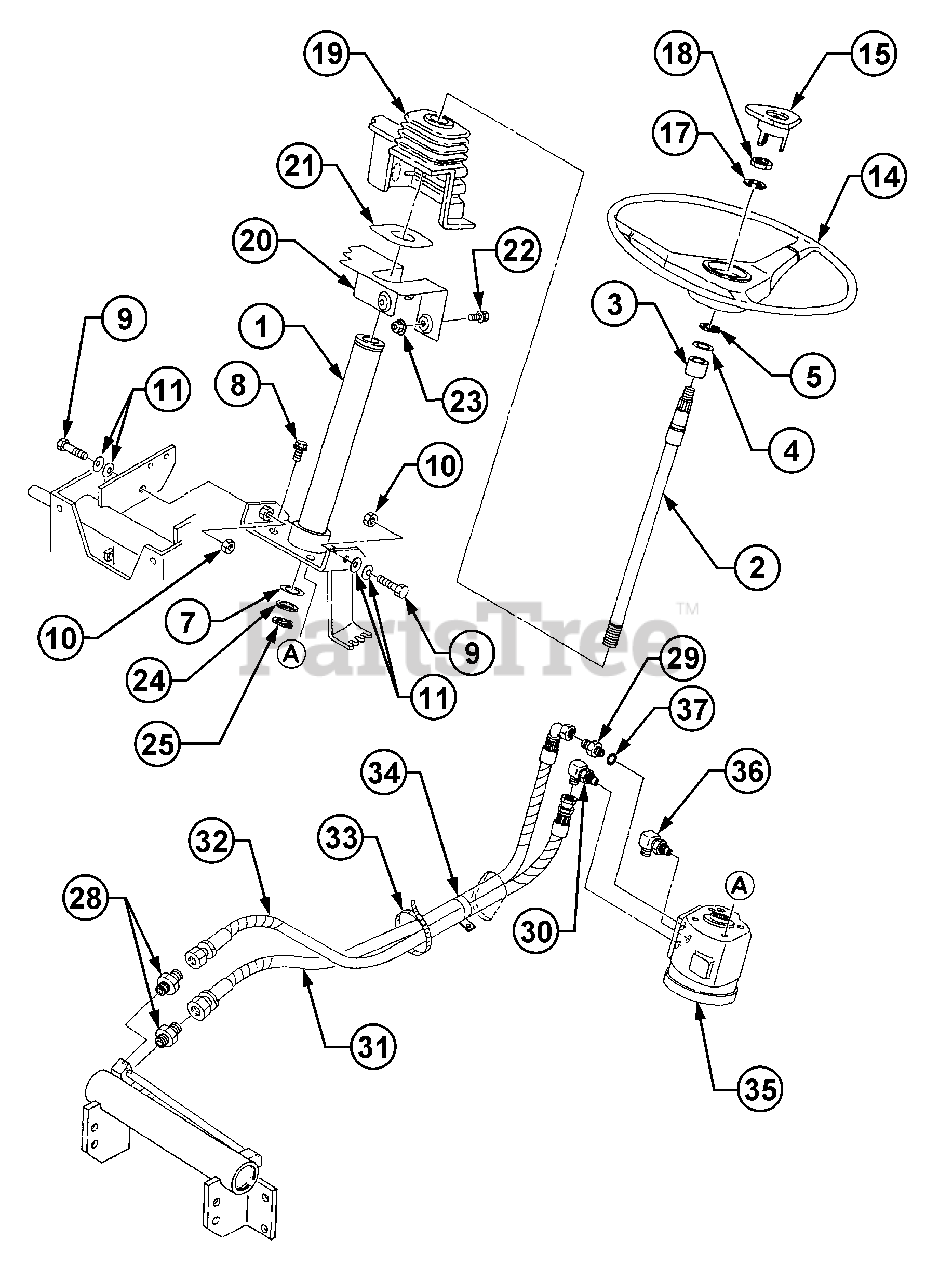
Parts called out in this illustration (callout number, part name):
2	Shaft, Steering
3	Bushing, Column
8	Bolt, w/Washer
11	Spring, Conical
14	Wheel, Steering
17	Washer, Spring
19	Boot, Steering
30	Elbow, 90 degree
35	Steering Unit
